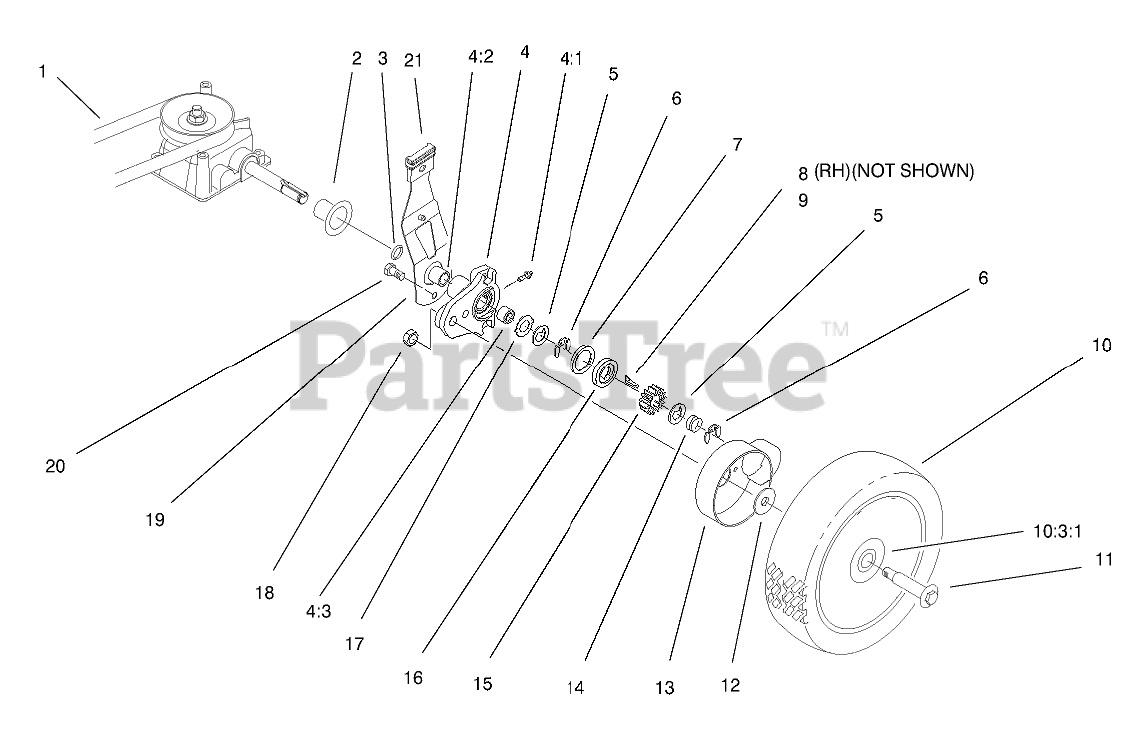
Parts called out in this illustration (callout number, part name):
1	V-BELT
2	CAP-END
3	O-RING
4	PIVOT ARM ASM
4:1	FITTING-GREASE
4:2	BEARING-ROLLER
4:3	BUSHING
5	WASHER-THRUST, KEYED
6	RING-CLIP, LOCKING
7	RING-FRICTION
8	KEY-ROCKING, RH
9	KEY-ROCKING, LH
10	WHEEL ASM
10	WHEEL AND TIRE ASM (W/GEAR)
10:3:1	BUSHING
11	BOLT-SHOULDER
11	BOLT-WHEEL
12	SPACER-COVER, WHEEL
13	COVER-WHEEL
14	SPRING-COMPRESSION
15	GEAR-PINION
16	WASHER-CLUTCH
17	WASHER-ARM, PIVOT
18	NUT-LOCK
19	SPRING ARM ASM
20	SCREW-HWH
21	KNOB-ARM
